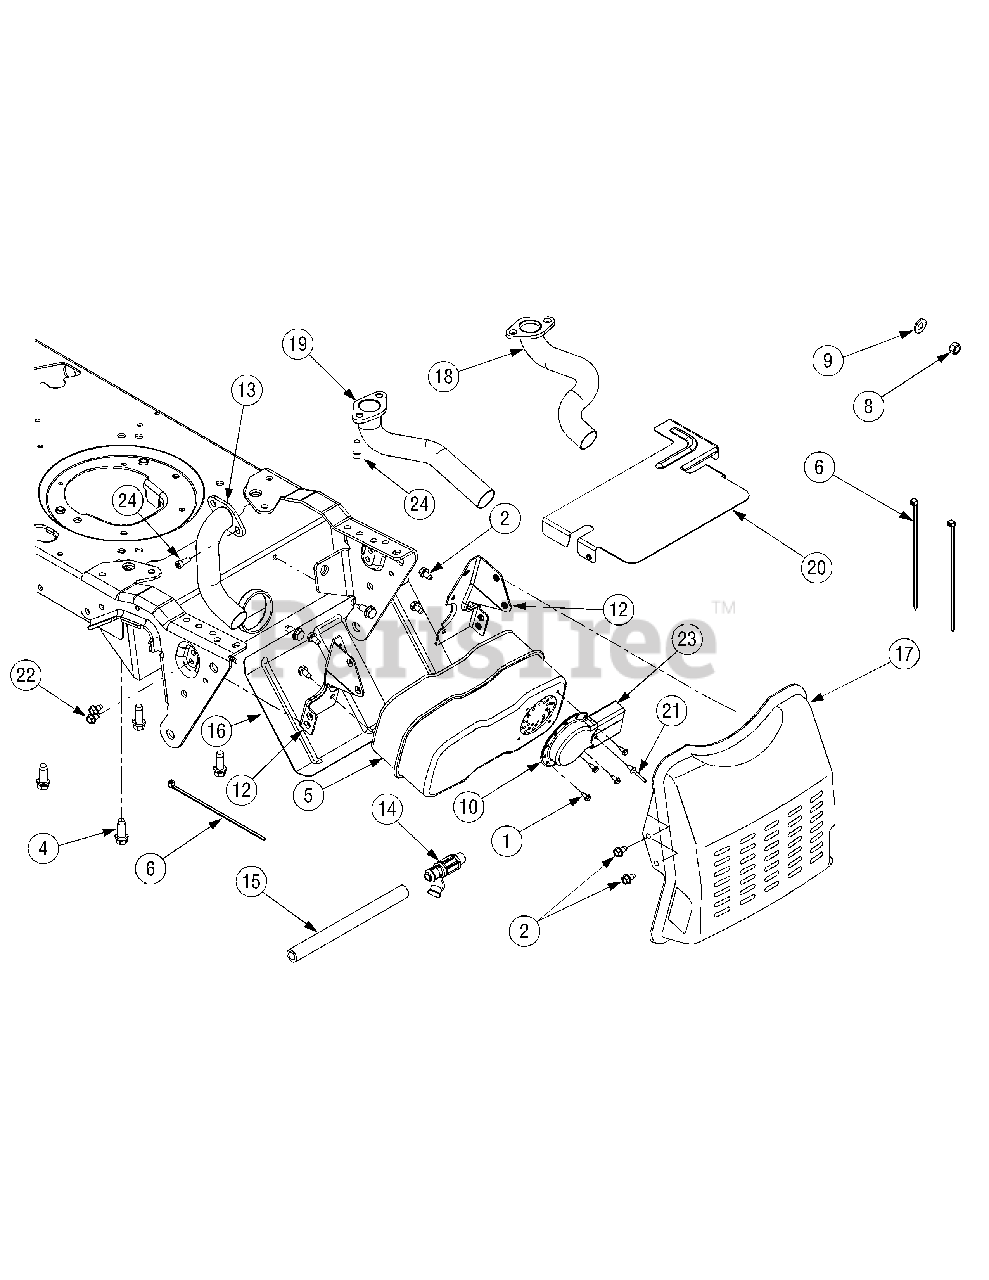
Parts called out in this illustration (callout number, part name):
1	Screw, #8-18, 0.500
2	Screw, Hex, 1/4-20, 0.500
3	Screw, Hex, 5/16-12 x .75
4	Screw, Hex, 3/8-16 x 1.00
4	Screw, Hex, 3/8-16 x 1.25
5	Muffler, Single Inlet
5	Muffler, Dual Inlet
6	Cable, Tie, 3/16 x .05 x 7.4
7	HEX FLANGE NUT
8	Hex Flange Nut, 3/8-16
9	Lock Washer,.406 x.875 x.059
10	Deflector, Muffler
14	Drain, Oil
15	Extension Hose, Oil Drain
16	Heat Shield, Lower
17	Shield, Muffler
18	Pipe, Exhaust, LH
19	Pipe, Exhaust, RH
20	Heat Shield, Upper
21	Rivet, Pop, .188 x .325
22	Screw, Hex, 1/4-20, 0.750
23	Extension, Deflector
24	Screw, 5/16-18, 0.75
